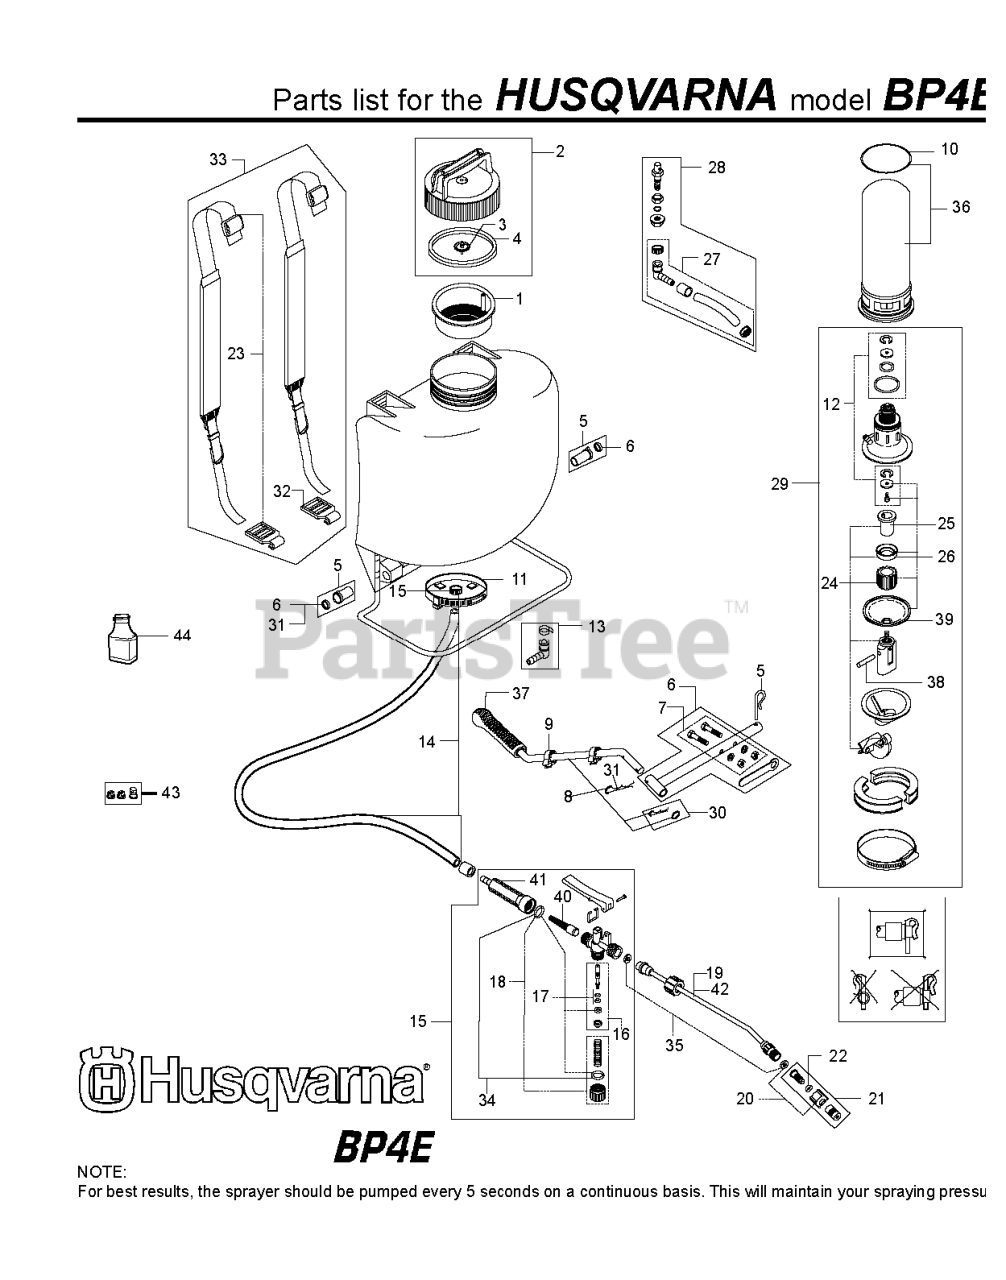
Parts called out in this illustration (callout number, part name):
1	TANK STRAINER
2	LID ORANGE W/LID & CARRY HNDL
4	CHECK VALVE FOR CAP
5	NYLON BEARING
6	PUMP LEVER
7	SCREW AND NUT SET
8	HANDLE PUMP FOLDBACK W/BALLGRP
10	PRESSURE TANK O-RING
11	RETENTION CLAMP
12	O-RING & WASHER SET FOR DIAP
13	90 DEGREE FITTING & CLAMP
14	HOSE AND 2 HOSE CLAMPS
15	COMP SPRAY PISTOL WBUILTNFILTE
16	SPINDLE SET
17	SPINDLE O-RING SET
19	BRASS SPRAY WAND 20"
20	NOZZLE HOLDER
21	ADJ BRASS NOZZLE WITH HOLDER
22	SPRAY TIP O-RING SET
23	BELT HOOK AND BUCKLE
24	HOLDER PISTON PUMP & GUIDE
25	KIT PISTON, DIAPHRAGM & SEALS
26	CUP PISTON VITON
27	HOSE AGITATING & CLAMPS
28	HOSE AGITATING CLAMPS & CONNEC
29	PUMP MODULE COMPLETE
30	LOCKING PIN-PUMP HANDLE (SML)
31	LOCKING PIN-PUMP HANDLE (LG)
33	HVY DTY PAD'D ADJ SHLDER STRAP
34	O RING FOR PLUG
35	WASHER SET FOR GUN & NOZZLE
36	SPEC SOLV REST PRESS CHAMBER
37	HANDLE
38	PIN FOR LEVER PUMP
39	HYTREL DIPHRAGM MEMBRANE
40	FILTER FOR KIT 18F
41	GRIP HANDLE FOR KIT 18F
42	SPRAY WAND 20" PLASTIC
43	PLASTIC SPRAY TIP SET (2-8004)
44	SILICONE GREASE ALL SPRAYERS
